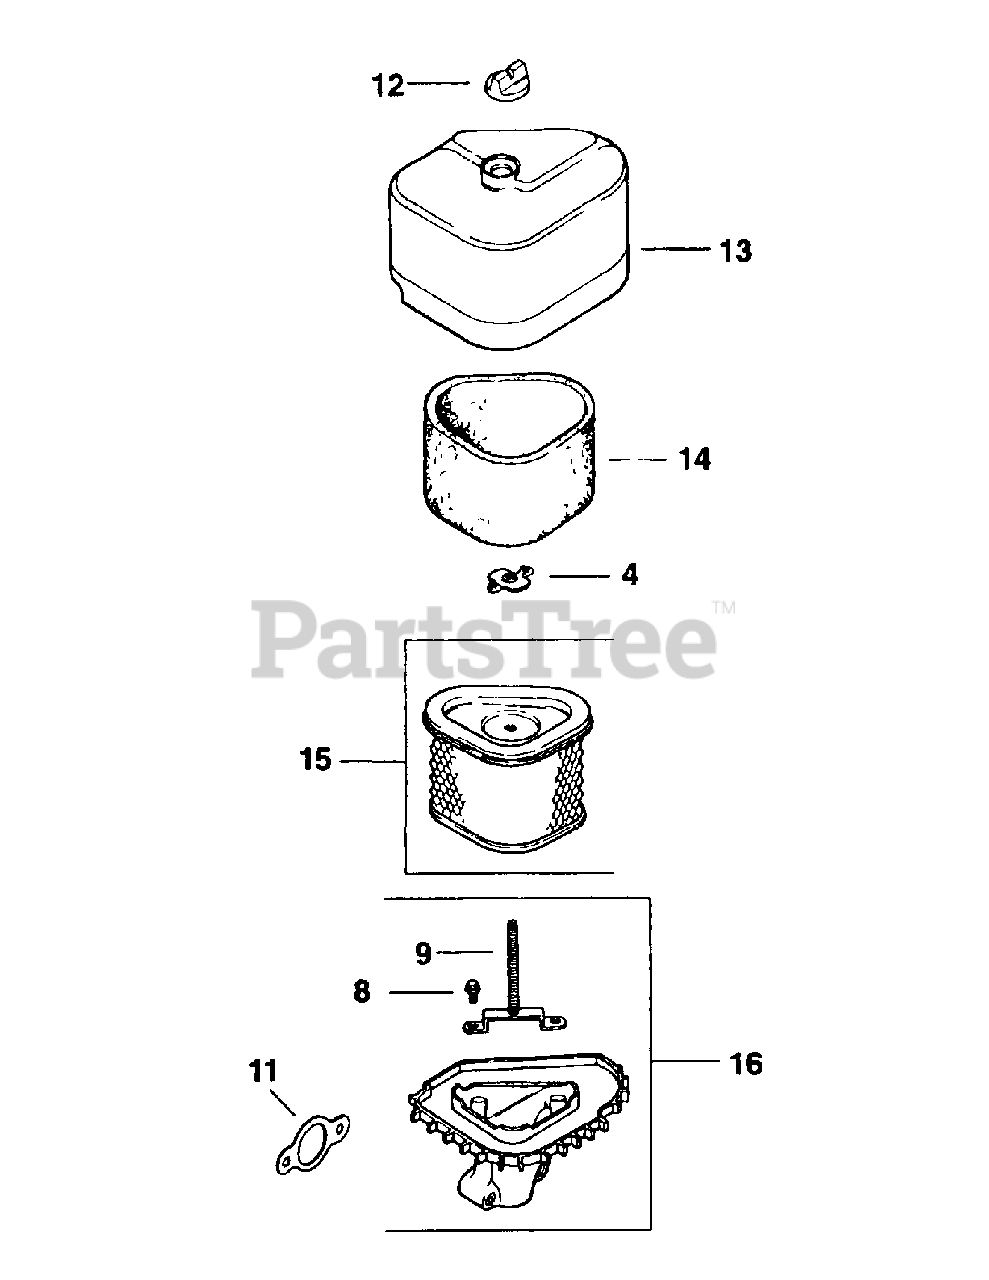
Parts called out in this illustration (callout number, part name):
4	Nut, Wing
8	Screw, Hex Cap #10 Hi-Lo
9	Stud, Mounting Plate
11	Gasket, Air Cleaner
12	Knob, Air Cleaner Cover
13	Cover, Air Cleaner
14	Precleaner
15	Elements, Air Cleaner & Precleaner
16	Base, Air Cleaner
